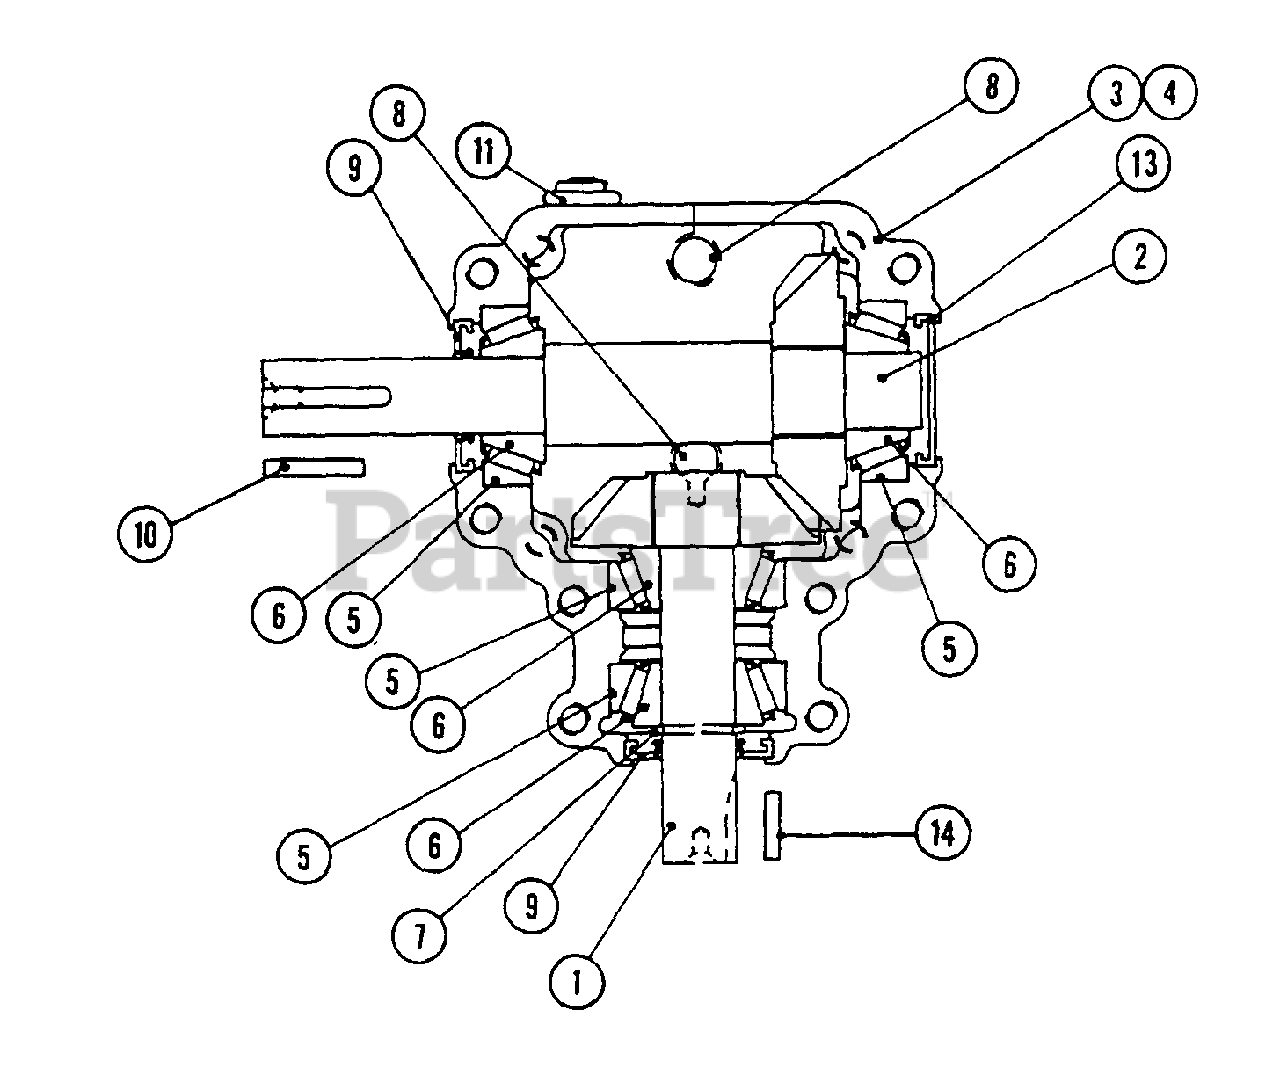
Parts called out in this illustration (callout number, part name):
1	SHAFT - pinion, with gear
2	SHAFT - cross, with gear
3	HOUSING - with tapped holes
5	CUP - bearing
6	CONE - bearing
7	RING - retaining
8	PLUG - pipe 1/4"
10	KEY - 3/16" x 1" input shaft
11	PIPE - vent
13	CAP - end
14	KEY - 3/16" x 5/8" output shaft
